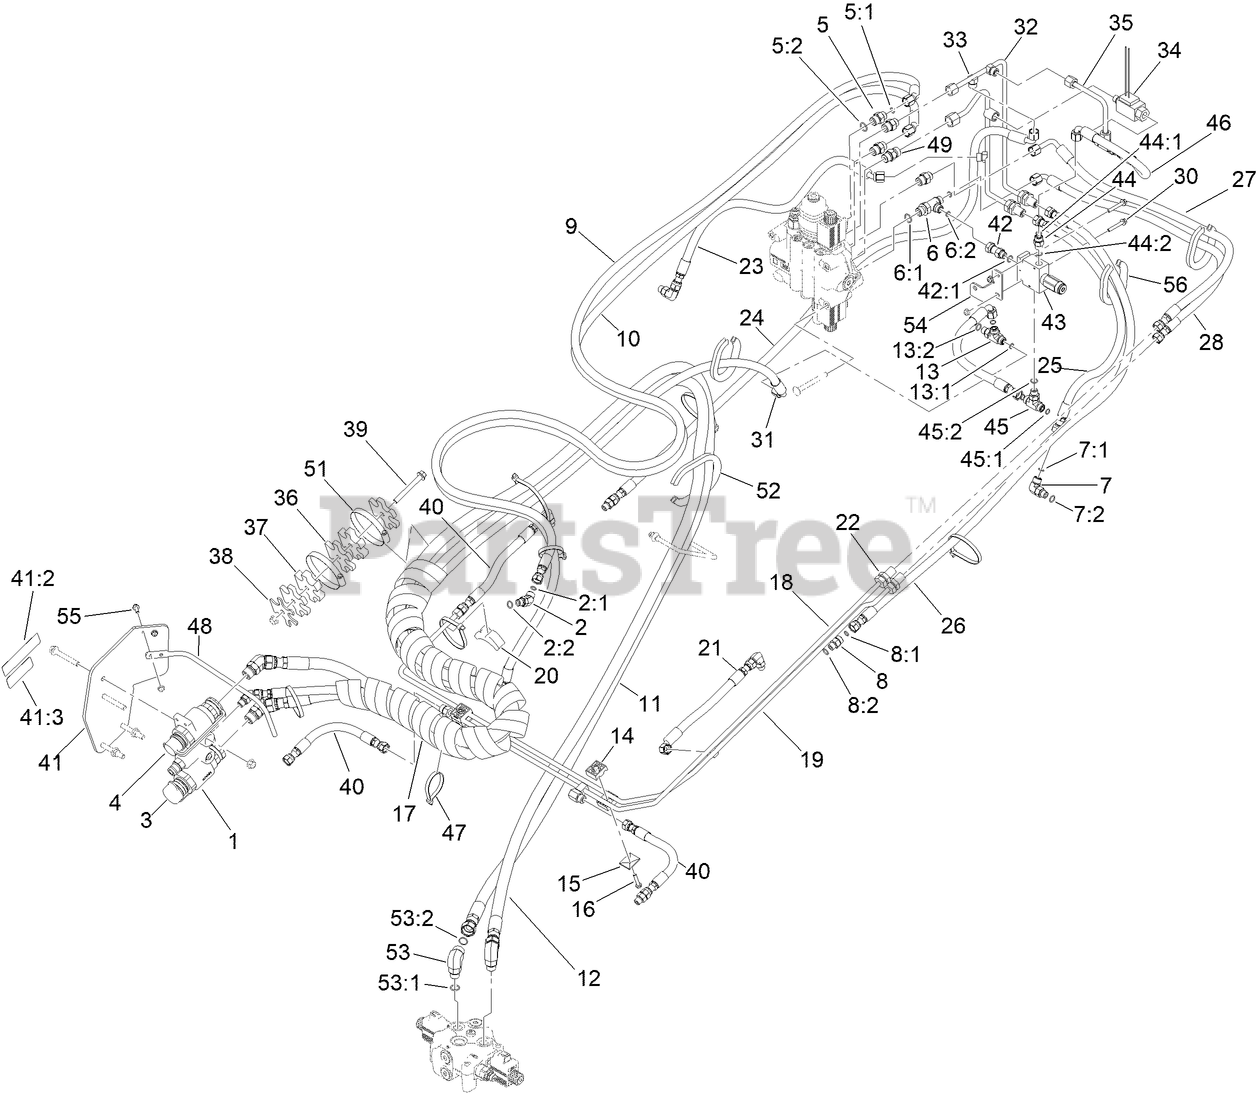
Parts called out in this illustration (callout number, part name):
1	MANIFOLD-QDC
2	FITTING-ELBOW, 45 DEG
2:1	O-RING
2:2	O-RING
3	CAP-DUST, COUPLER
4	CAP-DUST, NIPPLE
5	FITTING-STRAIGHT
5:1	O-RING
5:2	O-RING
6	FITTING-HYD, TEE
6:1	O-RING
6:2	O-RING
7	FITTING-ELBOW, 90 DEG
7:1	O-RING
7:2	O-RING
8	FITTING-STRAIGHT
8:1	O-RING
8:2	O-RING
9	HYD HOSE ASM
10	HYD HOSE ASM
11	HYD HOSE ASM
12	HYD HOSE ASM
13	FITTING-TEE
13:1	O-RING
13:2	O-RING
14	CLAMP-HOSE
15	PLATE-CLAMP, RETAINER
16	SCREW-HH
17	WRAP-HOSE
18	HYD TUBE ASM
19	HYD TUBE ASM
20	BLOCK-HARDLINE
21	HYD HOSE ASM
22	NUT-LOCK
23	HYD HOSE ASM
24	HYD HOSE ASM
25	HYD HOSE ASM
26	HYD HOSE ASM
27	HYD HOSE ASM
28	HYD HOSE ASM
30	SCREW-HHF
31	HYD HOSE ASM
32	HYD TUBE ASM
33	HYD TUBE ASM
34	SWITCH-PRESSURE,
35	HYD TUBE ASM
36	CLAMP-HOSE
37	CLAMP-HOSE
38	PLATE-BACKER
39	SCREW-HHF
40	HYD HOSE ASM
41	MOUNT-QC
41:2	DECAL-CAUTION
41:3	DECAL-WARNING, HYD PRESSURE
42	CONNECTOR-SWIVEL, STRAIGHT
42:1	O-RING
43	VALVE-SEQUENCE
44	FITTING-STRAIGHT
44:1	O-RING
44:2	O-RING
45	ADAPTER
45:1	O-RING
45:2	O-RING
46	HYD HOSE ASM
47	TIE-CABLE
48	GUIDE-HOSES
49	VALVE-CHECK
51	CLAMP-BAND/SCREW
52	TRIM-SEAL
53	FITTING-ELBOW, 90 DEG
53:1	O-RING
53:2	O-RING
54	BRACKET-MOUNT, VALVE
55	SCREW-HHF
56	TRIM-SEAL
